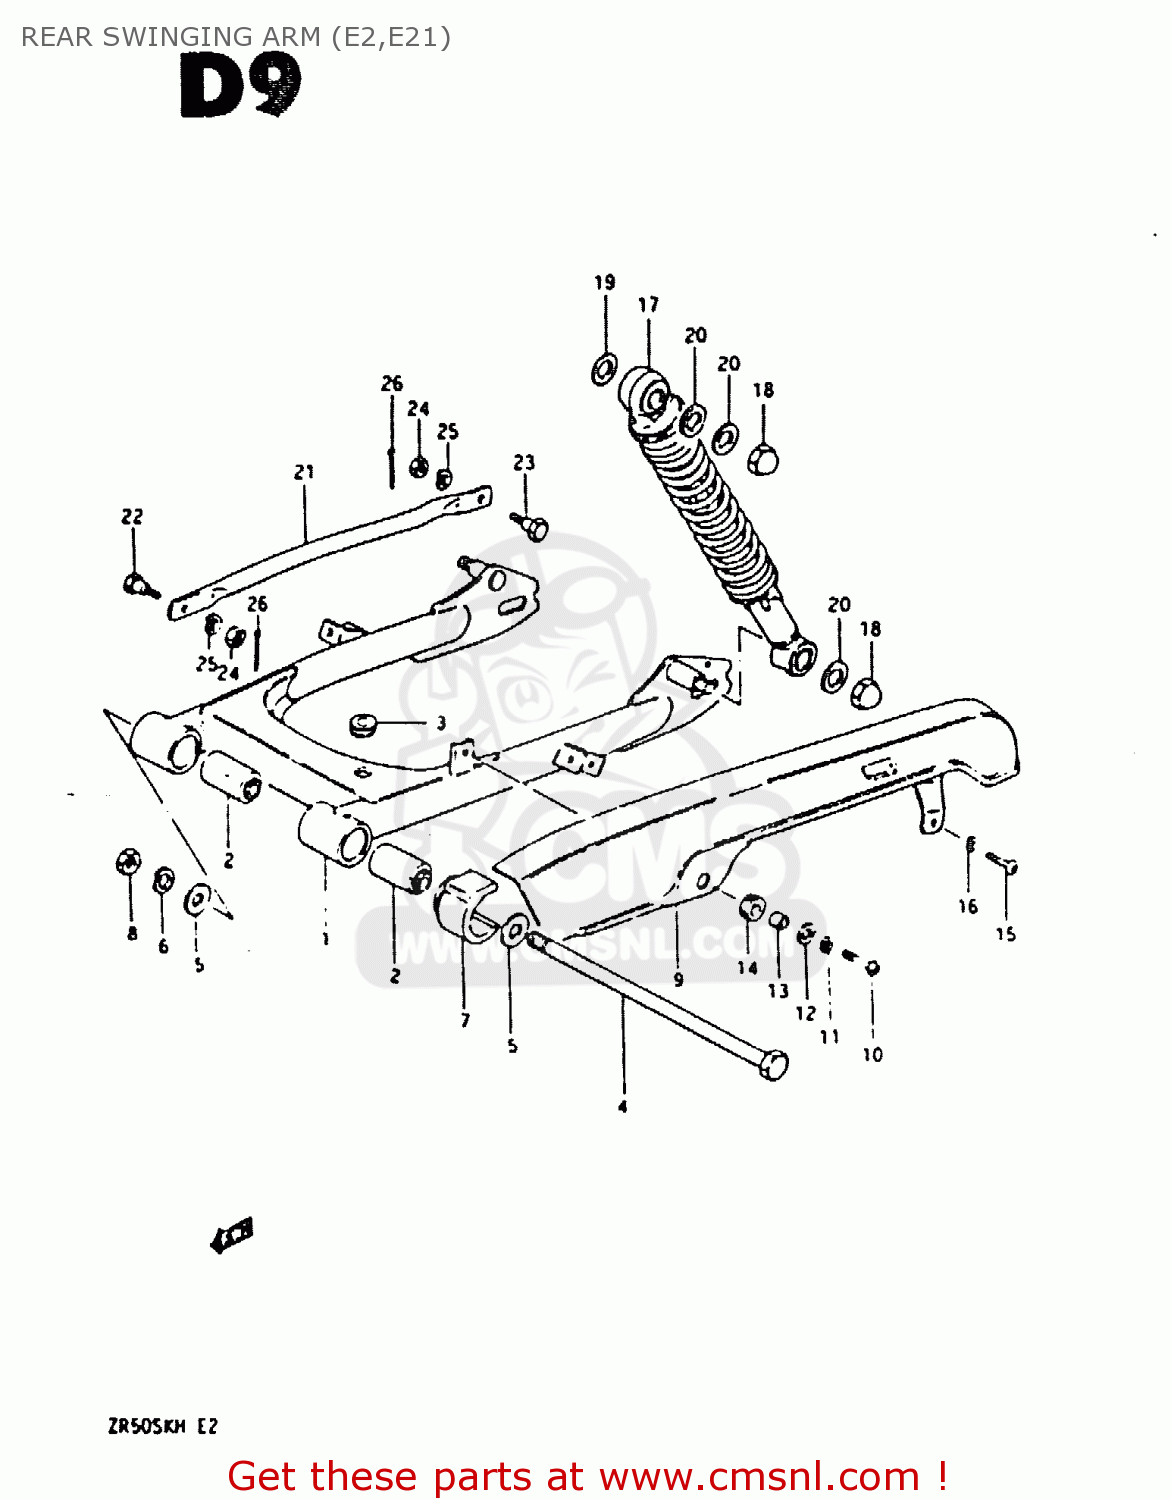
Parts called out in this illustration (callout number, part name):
1	SWINGING ARM SET, REAR
2	BUSH
3	CUSHION
4	SHAFT,RR SHOCK ABSORBER UPR
5	WASHER
6	WASHER,LOCK,10
7	BUFFER,CHAIN TOUCH DEFENSE
8	NUT
9	CHAIN CASE
10	SCREW
11	WASHER,LOCK
12	WASHER (6.5X20X1.2)
13	SPACER (7X9X7)
14	CUSHION
15	SCREW
16	WASHER,LOCK
17	SHOCK ABSORBER, REAR
18	NUT, LOWER LH
19	WASHER
20	WASHER
21	TORQUE LINK, REAR (BLACK)
22	BOLT(8X22)
23	BOLT(8X26.5)
24	NUT
25	LOCK WASHER
26	PIN 20X20
